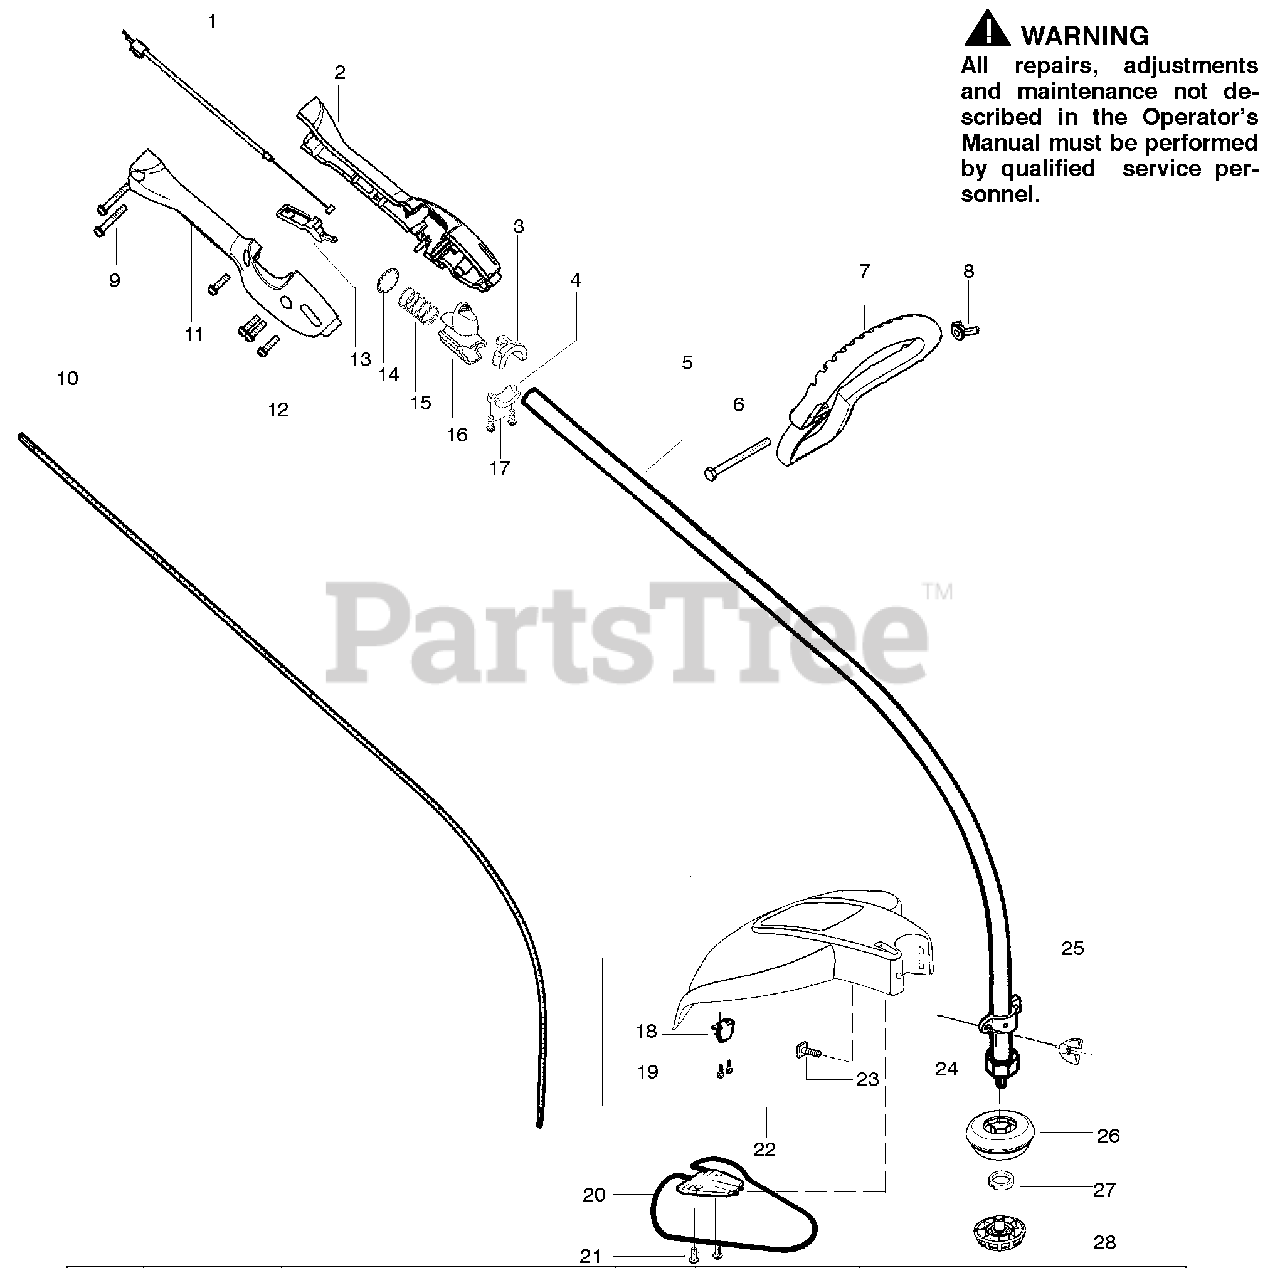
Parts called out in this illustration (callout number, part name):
1	Assy-Throttle Cable
2	Throttle Hsg. (Left)
3	Locator- left
4	Locator- right
5	Kit-Drive Shaft Assy.
6	Bolt-Handle
7	Handle-Assist
8	Wingnut-Handle
10	Shaft- Flex
11	Throttle Hsg. (Right)
14	Nut-Push
15	Spring-Actuator
16	Actuator
17	Screw
18	Line Limiter
19	Screw-Line Limiter
20	Assy-Wire Guard
22	Kit-Shield
23	Bolt-Shield
24	Dust Cup
25	Wingnut
26	Accy- Spool w/Line
27	Guide-Line
28	Assy-Cap
